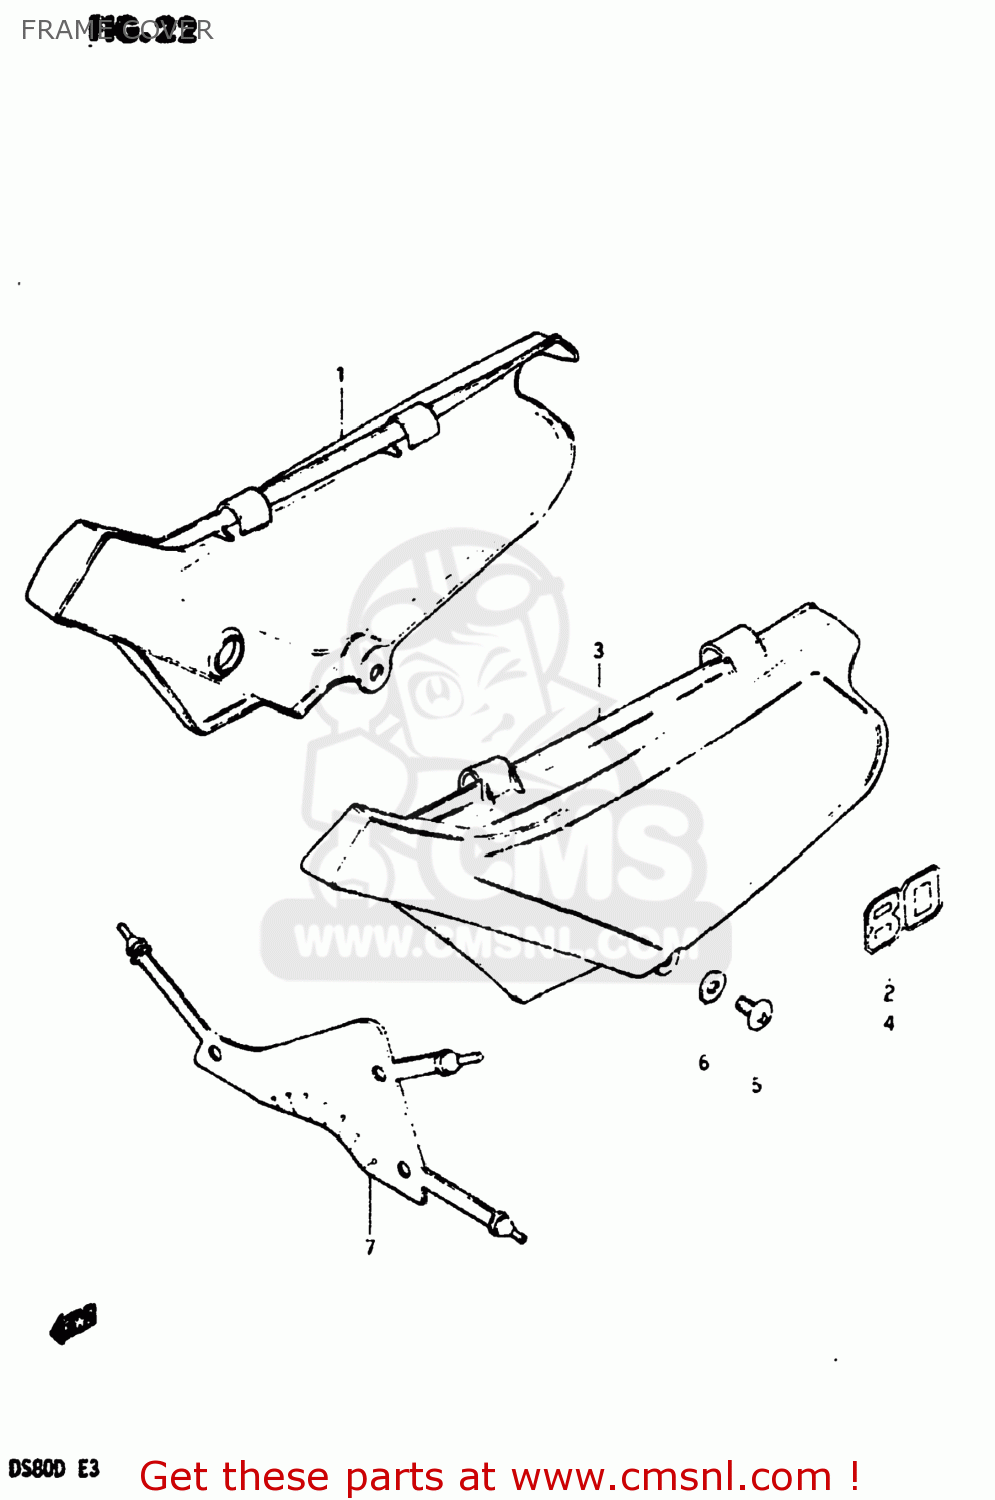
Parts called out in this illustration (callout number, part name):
1	COVER,FRAME,RIGHT
2	EMBLEM,FRAME COVER RH
3	COVER,FRAME,LEFT
4	EMBLEM,FRAME COVER,LEFT
5	SCREW
6	WASHER(6.5X16X1.2)
7	MUD GUARD,FRAME COVER
